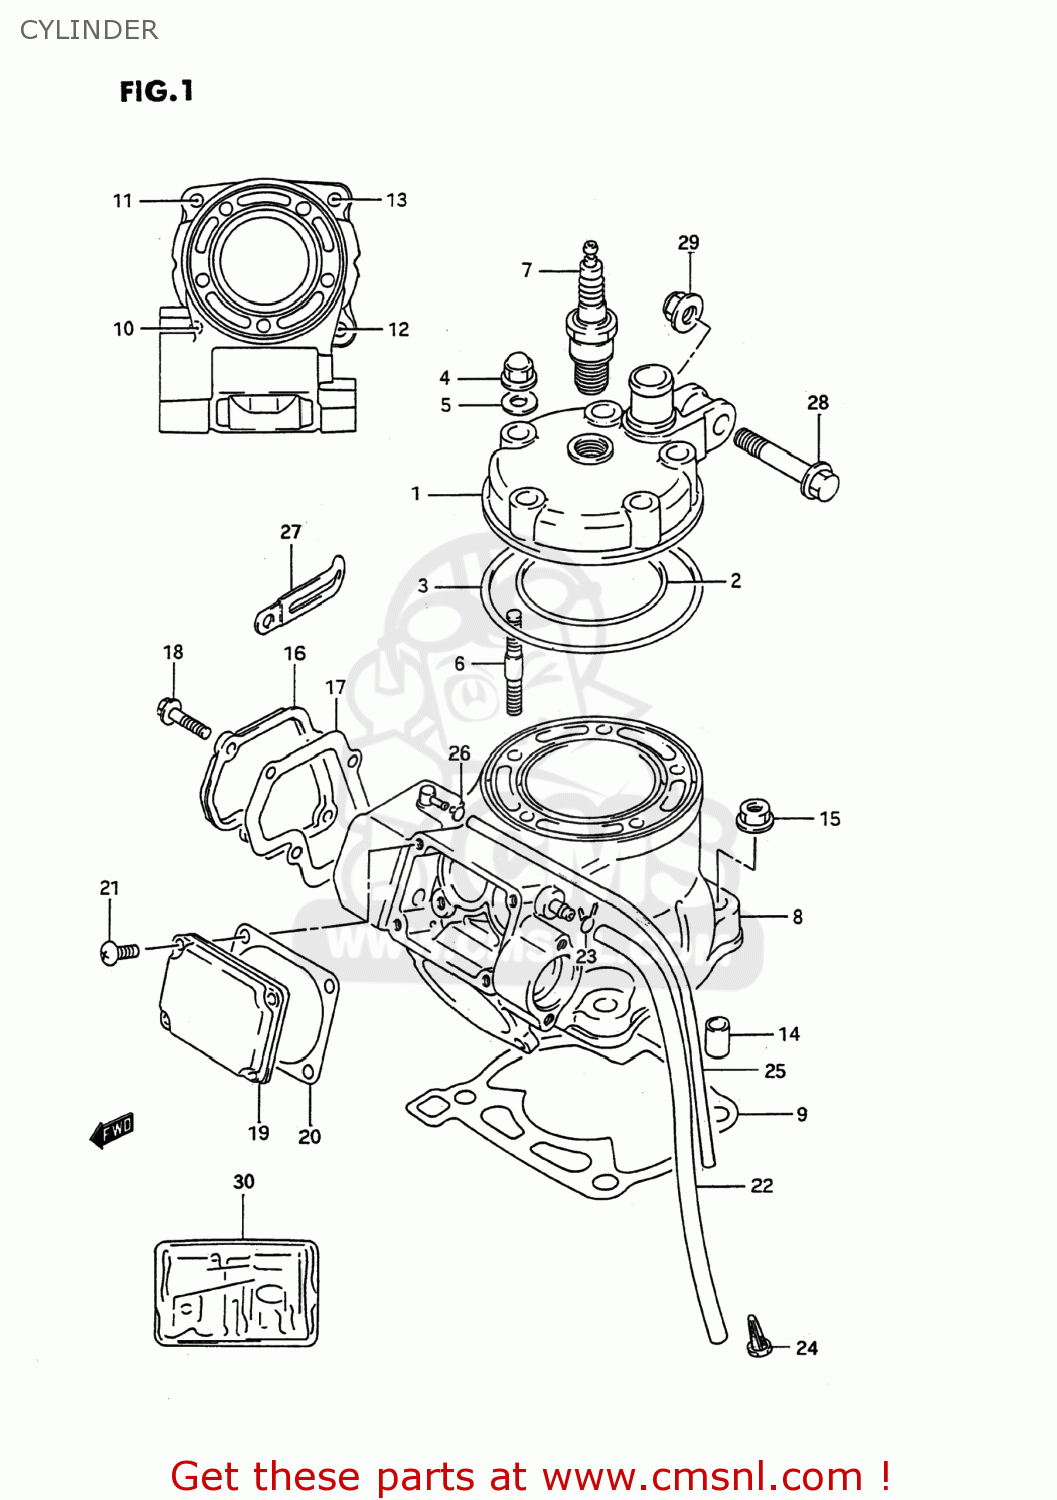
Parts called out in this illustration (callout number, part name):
1	HEAD,CYLINDER
2	O RING,CYLINDER HEAD NO.1
3	O RING,CYLINDER HEAD NO.2
4	NUT
5	GASKET(8.5X17X2.3) (NAS)
6	BOLT,STUD
7	PLUG,SPARK(R4118S-9)
8	CYLINDER
9	GASKET,CYLINDER (NAS)
10	STUD 8X25
11	BOLT,STUD
12	STUD BOLT
13	BOLT,STUD
14	PIN(8.4X11X14)
15	NUT
16	COVER,CYLINDER NO.1
17	GASKET,CYLINDER COVER (NAS)
18	BOLT
19	COVER,CYLINDER NO.2
20	GASKET,CYLINDER COVER NO.2 (NAS)
21	BOLT
22	HOSE
23	CLIP
24	FILTER,EXH VALVE BREATHER HOSE
25	HOSE(5X8.2X600)
26	CLIP
27	CLAMP
28	BOLT(8X41)
29	NUT
30	GASKET SET (NAS)
